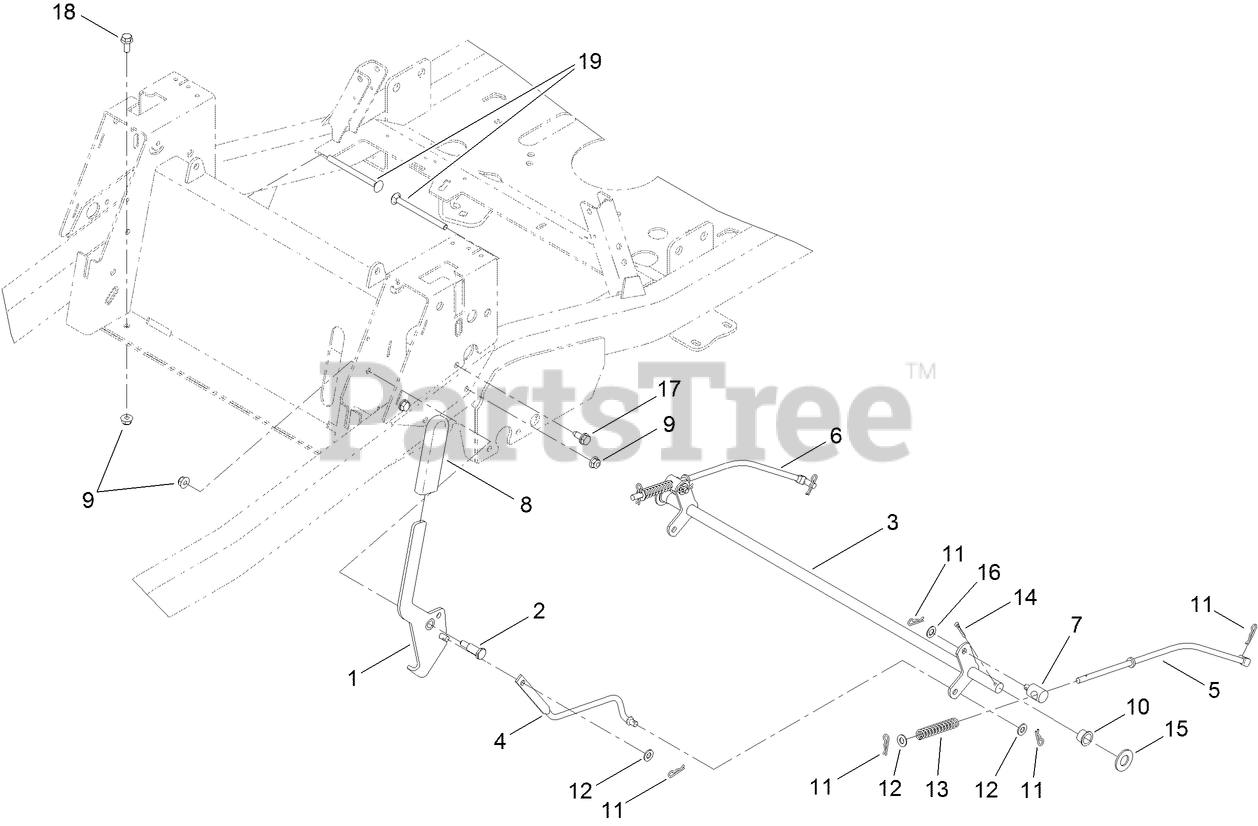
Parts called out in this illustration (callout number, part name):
1	HANDLE-BRAKE
2	SCREW-SHOULDER
3	BRAKE-BELLCRANK
4	LINK-BRAKE
5	ROD-BRAKE, LH
6	ROD-BRAKE, RH
7	FITTING-ROD
8	GRIP-LEVER
9	NUT-HF, NI
10	BUSHING-FLANGE, NI
11	PIN-COTTER
12	WASHER-PLAIN
13	SPRING-RETURN, NEUTRAL
14	PIN-COTTER
15	WASHER-FLAT
16	WASHER
17	SCREW-HWHTF
18	SCREW-HHF
19	SCREW-CARR
